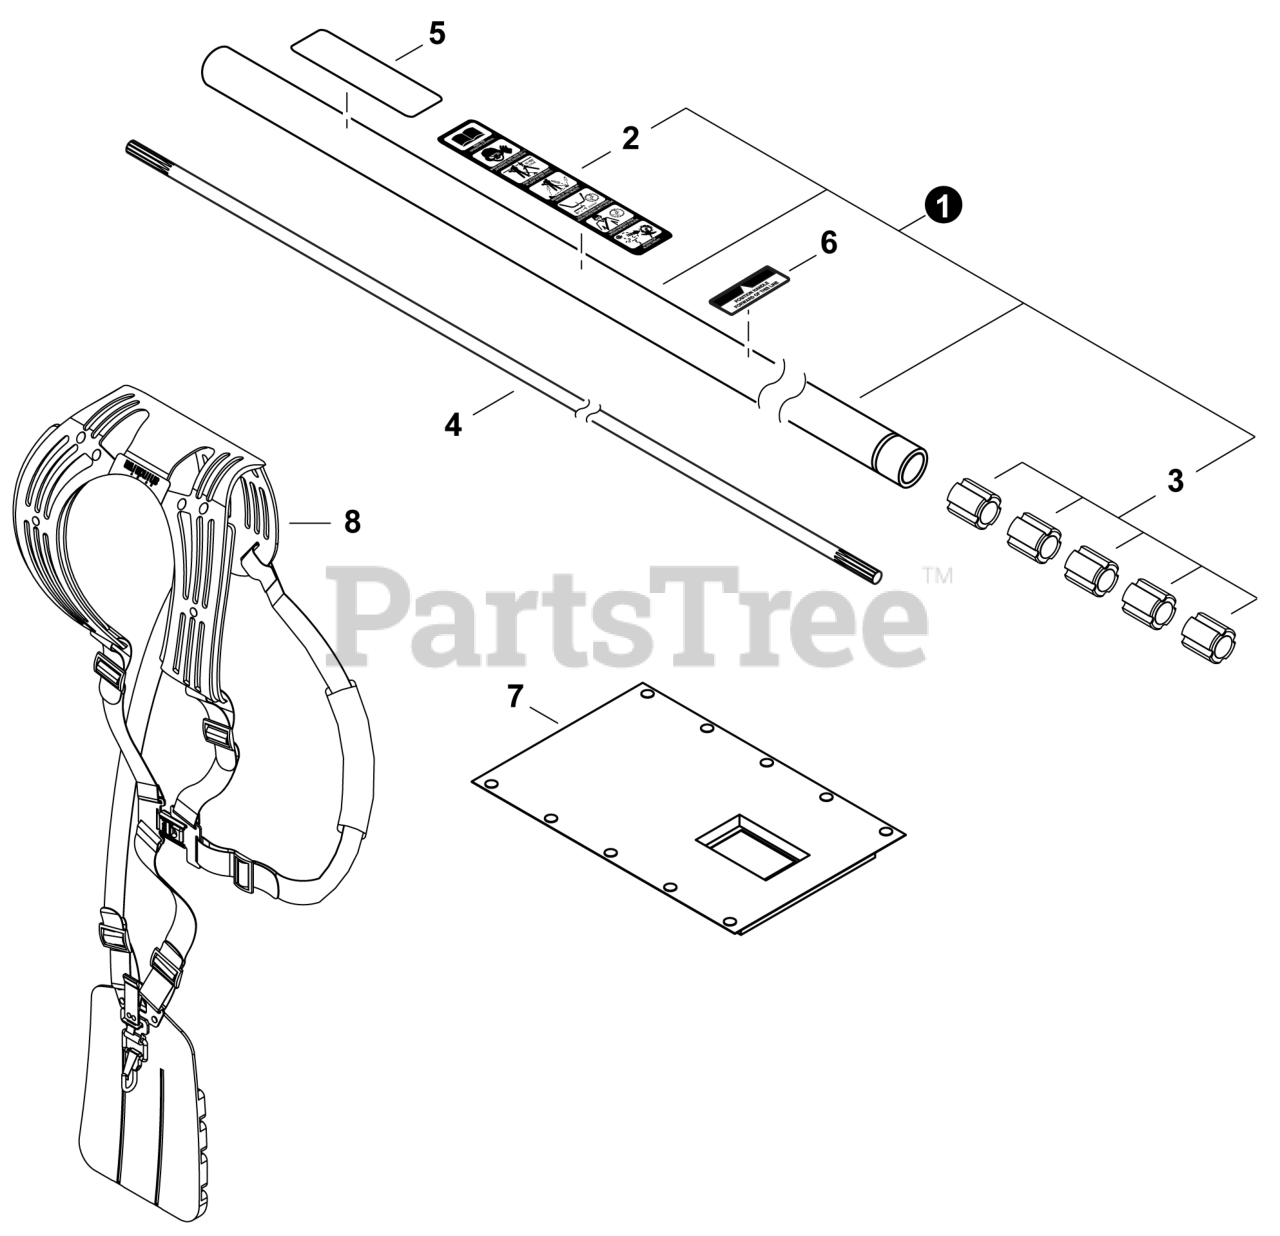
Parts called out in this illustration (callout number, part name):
1	MAIN PIPE ASSY
2	LABEL - CAUTION (BLADE CAPABLE)
3	BUSHING
4	DRIVESHAFT
5	LABEL - SHINDAIWA PROFESSIONAL
6	LABEL - ALIGNMENT
7	PROTECTOR
8	HARNESS ASSY
